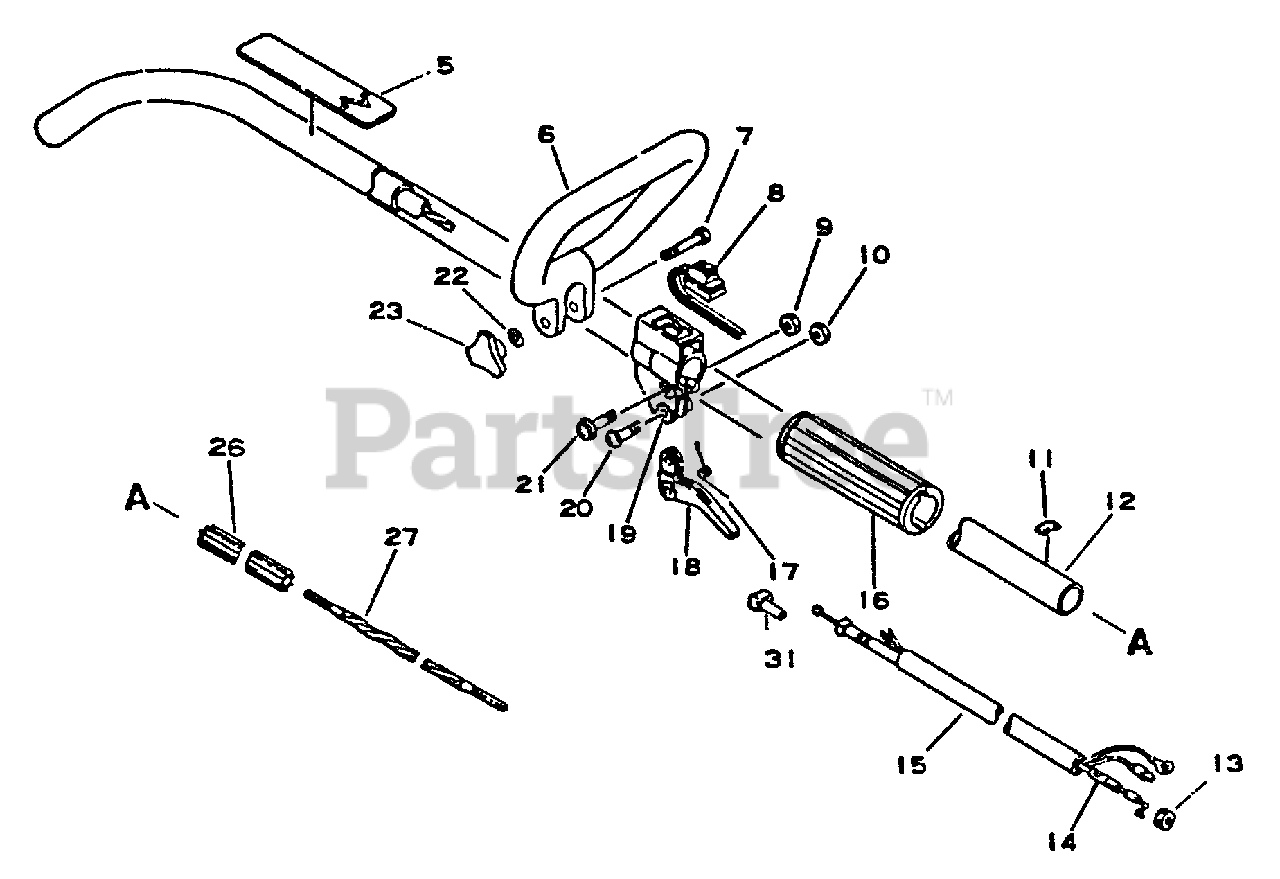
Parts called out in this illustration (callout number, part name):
5	LABEL - CAUTION
6	HANDLE
7	BOLT - 6X40
8	IGNITION SWITCH ASSY
10	LOCKNUT - 5
11	LABEL - ALIGNMENT
12	MAIN PIPE ASSY
14	CABLE, THROTTLE
15	TUBE - VINYL
16	GRIP, HANDLE
17	SPRING, TRIGGER
18	TRIGGER, THROTTLE
19	BRACKET, THROTTLE CONTROL
20	SCREW - 5X30
21	SCREW - 5X28
22	WASHER - 6
23	KNOB, FASTENER
26	LINER - FLEXIBLE
27	DRIVESHAFT - FLEXIBLE
31	GUIDE, CABLE
